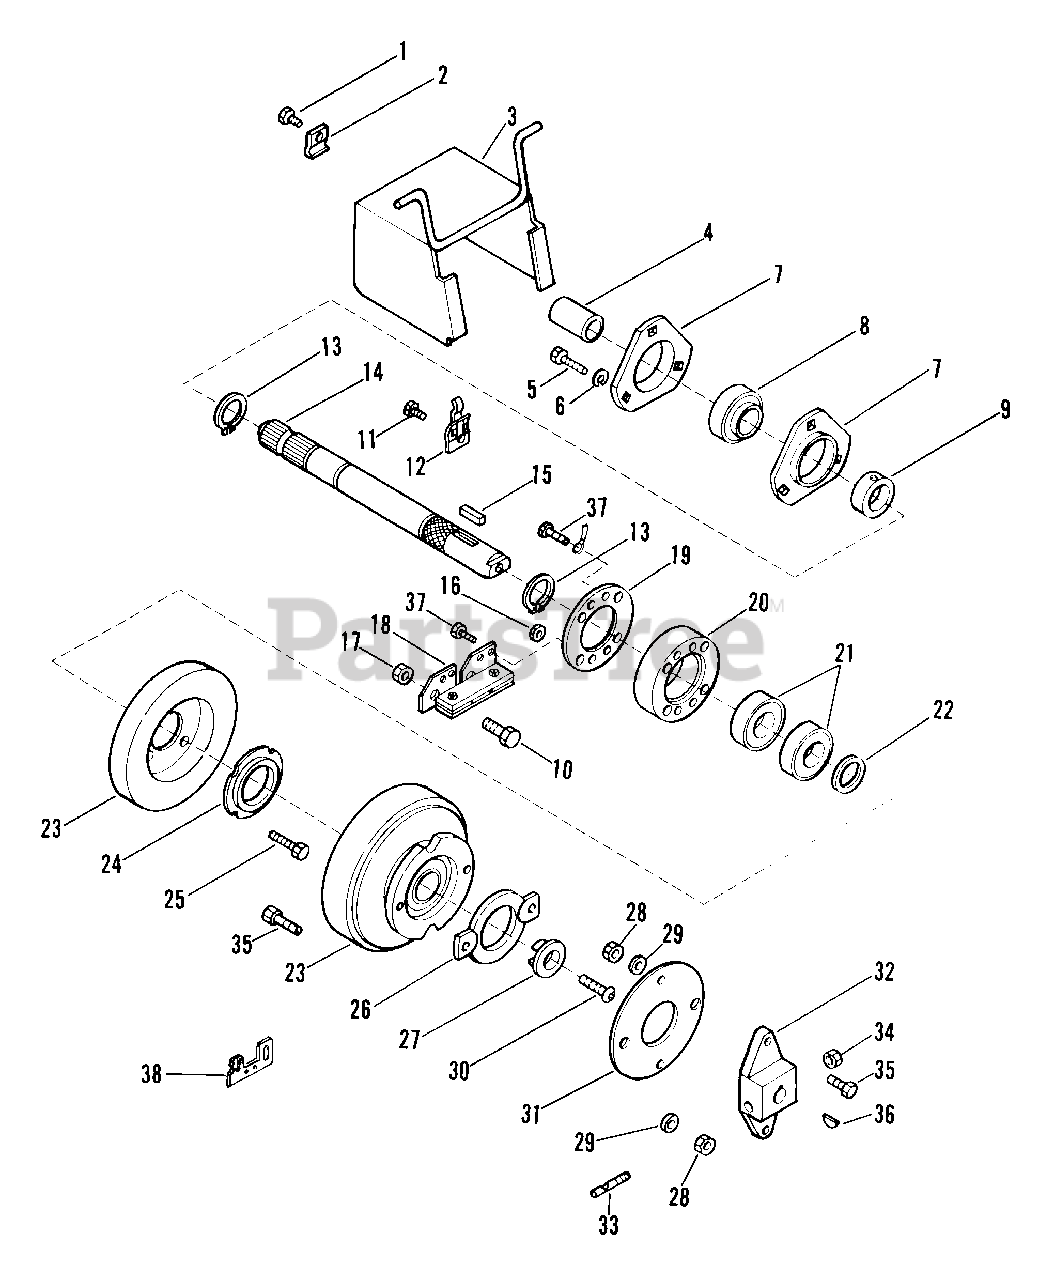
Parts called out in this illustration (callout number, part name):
1	SCR-TAP .250-20X.50 HXSLHDPL
3	PTO SHIELD
4	SHAFT COVER
5	BLT-HEX .31-18X.75 PL GR2
6	WSHR-LK .312X.097 PL HVY
7	BEARING FLANGE
8	BRG/W COLLAR 1.0 X 2.047 X.844
9	BEARING COLLAR
10	BLT-HEX .31-18X1.50 PL GR5
11	SCR-TAP 10-24X.375 HWH PL TR
12	SNAP FASTENER
13	RG-RTNG-EXT 1.00X.078
15	KEY-SQ .25X1.0X.25 SAE 8630
16	NUT-LK TOP 10-24 PL
17	NUT-LK-CTR .312-24 PL
18	TORQUE BRACKET ASSEMBLY
20	BEARING MOUNT
21	BRG-BALL 1.0X2.0X.56
22	WSHR-FL-STL 1.031X1.375X.055
23	ELECTRIC CLUTCH
24	BEARING FLANGE
25	SCR-MCH 10-24X1.25 SLPAN PL
26	PILOT PLATE
27	RETAINER
28	NUT-LK .312-18 GR A PL
29	WSHR-FL-STL.344X.688X.065PL
30	BLT-BTHD .38-16X1.25 GR5
31	SPACER COUPLING
32	COUPLING
33	LOCK STUD
34	NUT-LK TOP .375-16 GR C YWZC
35	BLT-HEX .31-18X.88 PL GR2
36	KEY-WDRF .188X.75X.313 SAE 9
37	SCR-TAP 10-24X.75 HWH PL TR
38	CONNECTOR MOUNTING CLIP
